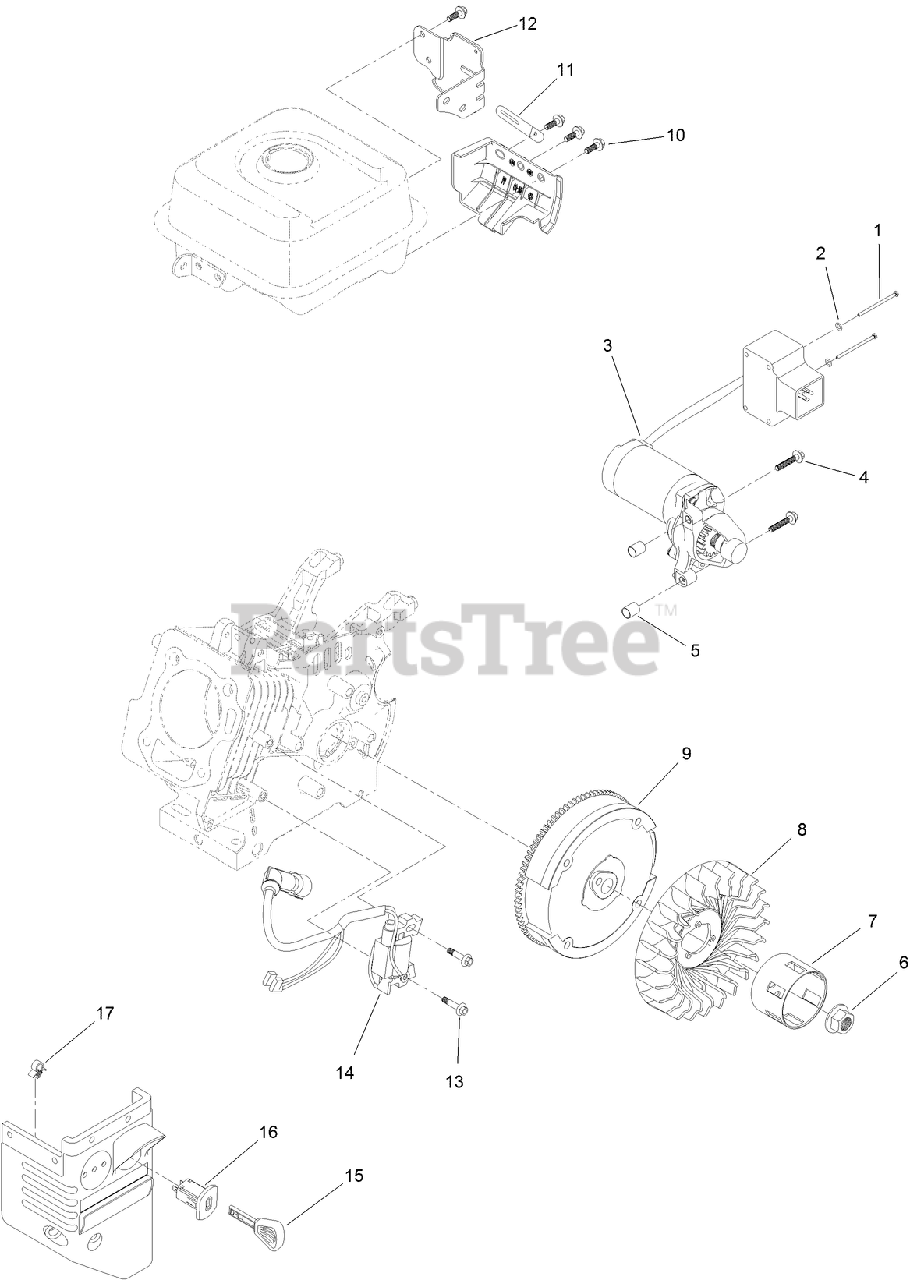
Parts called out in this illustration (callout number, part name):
1	SCREW-BHP
2	WASHER-PLAIN
3	MOTOR-STARTER
4	SCREW-FLANGE
5	PIN-DOWEL
6	NUT-FLANGE
7	CUP-STARTER
8	FAN-COOLING
9	FLYWHEEL AND RING GEAR ASM
10	SCREW-HHF
11	CLIP-HARNESS, WIRE
12	BRACKET-SWITCHBOX, STARTER
13	SCREW-HHF
14	IGNITION COIL ASM
16	SWITCH-KEY
